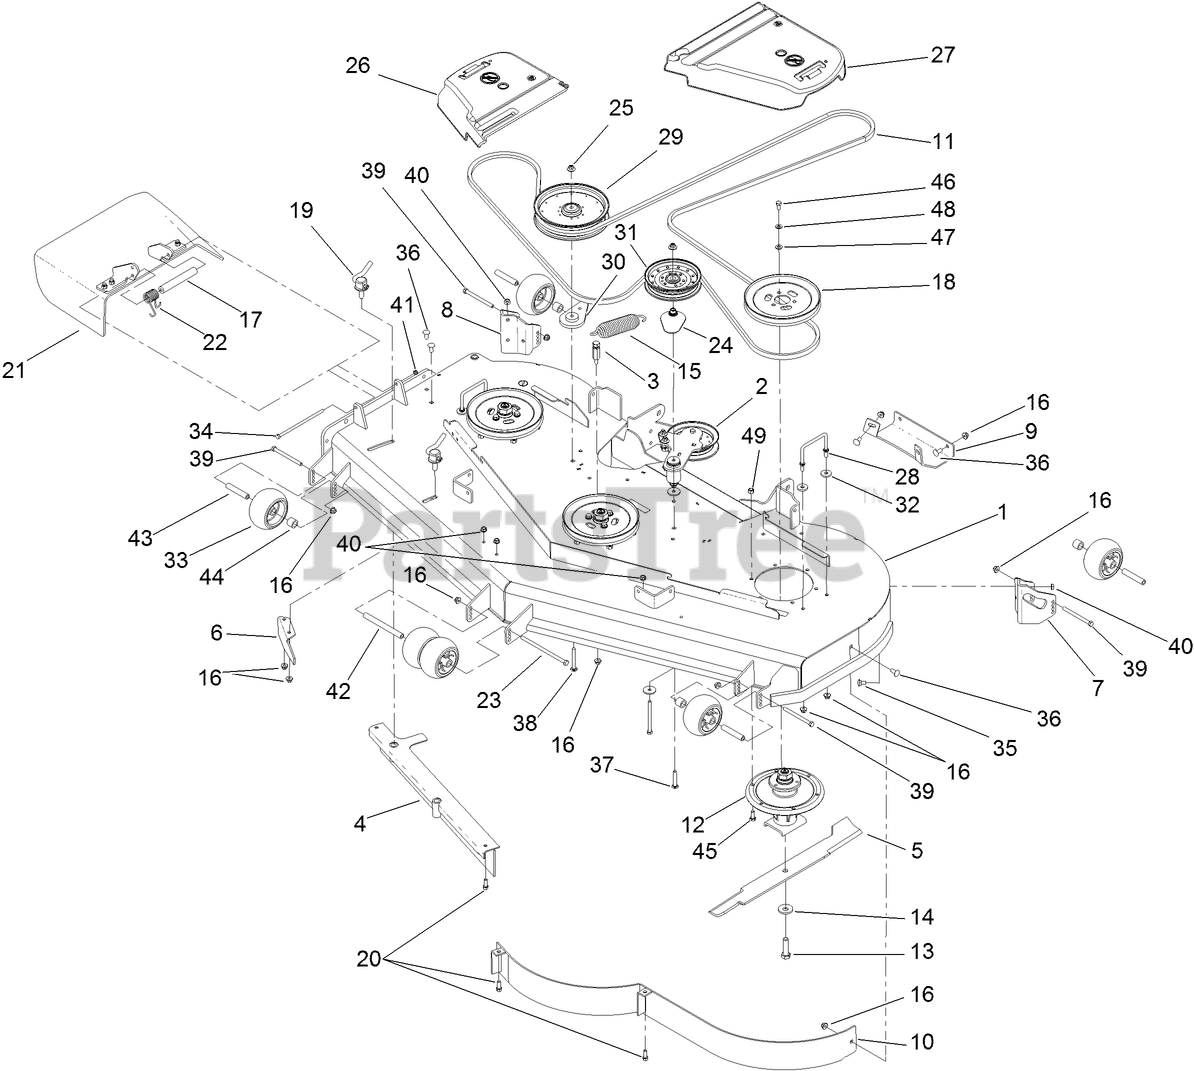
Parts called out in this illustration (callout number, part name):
1	DECK DECAL ASM
2	IDLER ARM ASM
3	ANCHOR-SPRING, TALL
5	BLADE-HI FLOW, 24.5 INCH
6	BAFFLE-DISCHARGE
7	MOUNT-WHEEL, LH
8	MOUNT-WHEEL, RH
9	PLATE-SKID
11	BELT-V
12	SPINDLE ASM
13	SCREW-BLADE
14	Washer-Blade Bolt, Heavy
15	EXTENSION-SPRING
16	NUT-HF, NI
17	SPACER
18	Pulley
19	LEVER ASM
20	SCREW-HWH
21	RUBBER DEFLECTOR ASM
22	SPRING-TORSION
23	SCREW-HH
24	SPACER-PULLEY
25	NUT-FLANGE, NI
26	COVER-BELT, RH
27	COVER-BELT, LH
28	WIREFORM-COVER
29	PULLEY-IDLER
30	SPACER-IDLER
31	PULLEY-IDLER, FLAT
32	WASHER
33	ROLLER-SCALP, ANTI
34	SCREW-HH
35	SCREW-CARR
36	SCREW-CARR
37	BOLT-CARR, SHORT NECK
38	SCREW-CARR
39	SCREW-HH
40	NUT-HHF, WHIZ
41	NUT-LOCK, NI
42	SPACER-WHEEL
43	TUBE-SPANNER
44	TUBE-SPACER
45	SCREW-HH
46	SCREW-HH
47	WASHER-FLAT
48	WASHER-BELLEVILLE
49	NUT-LOCK, NI
